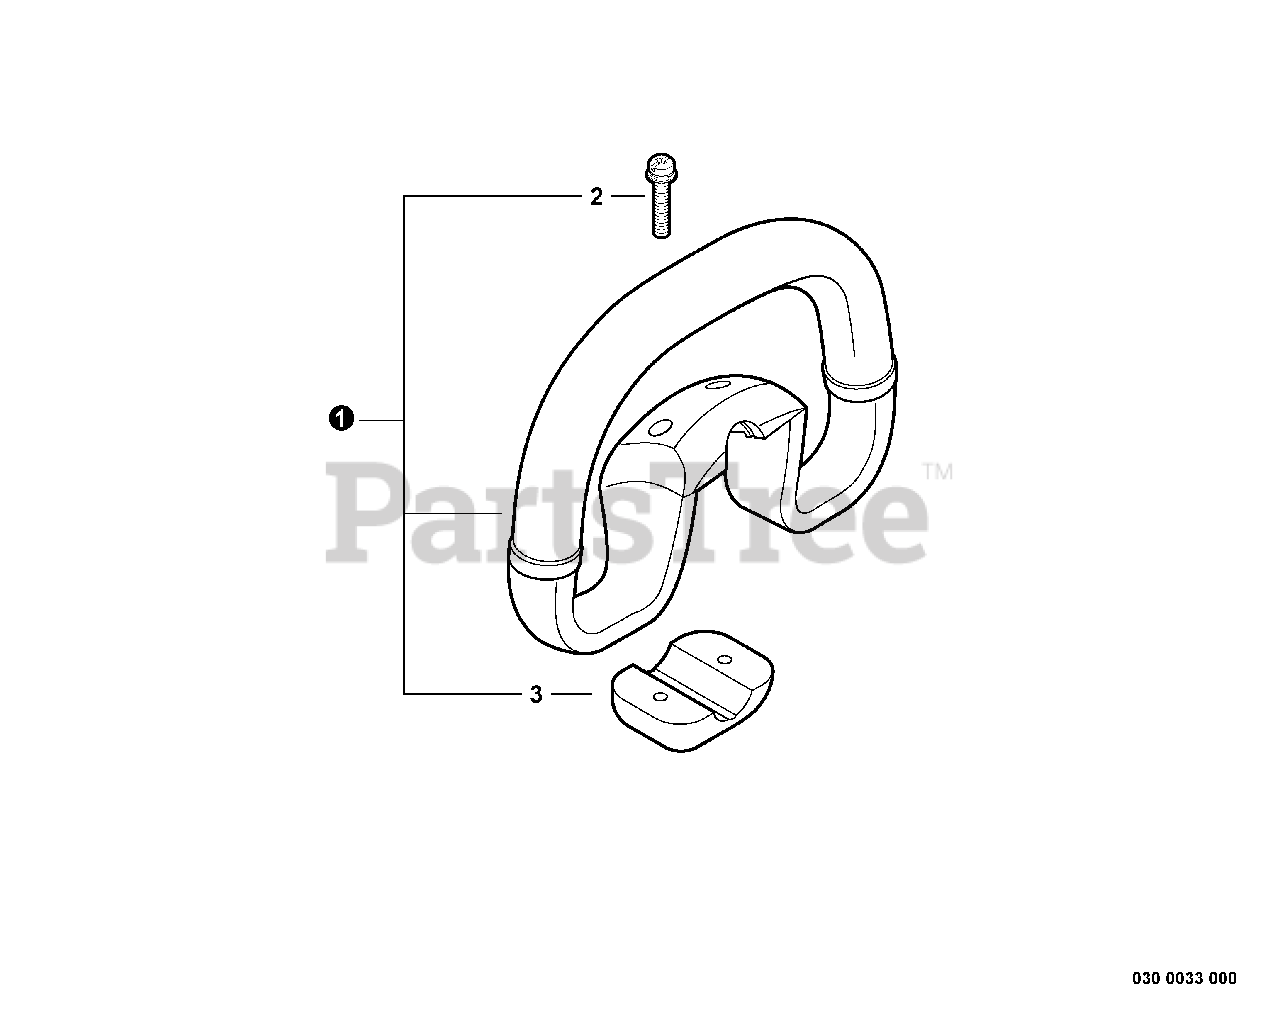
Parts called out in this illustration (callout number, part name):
1	HANDLE KIT - FRONT
2	SCREW - 5X40
3	BRACKET, HANDLE
